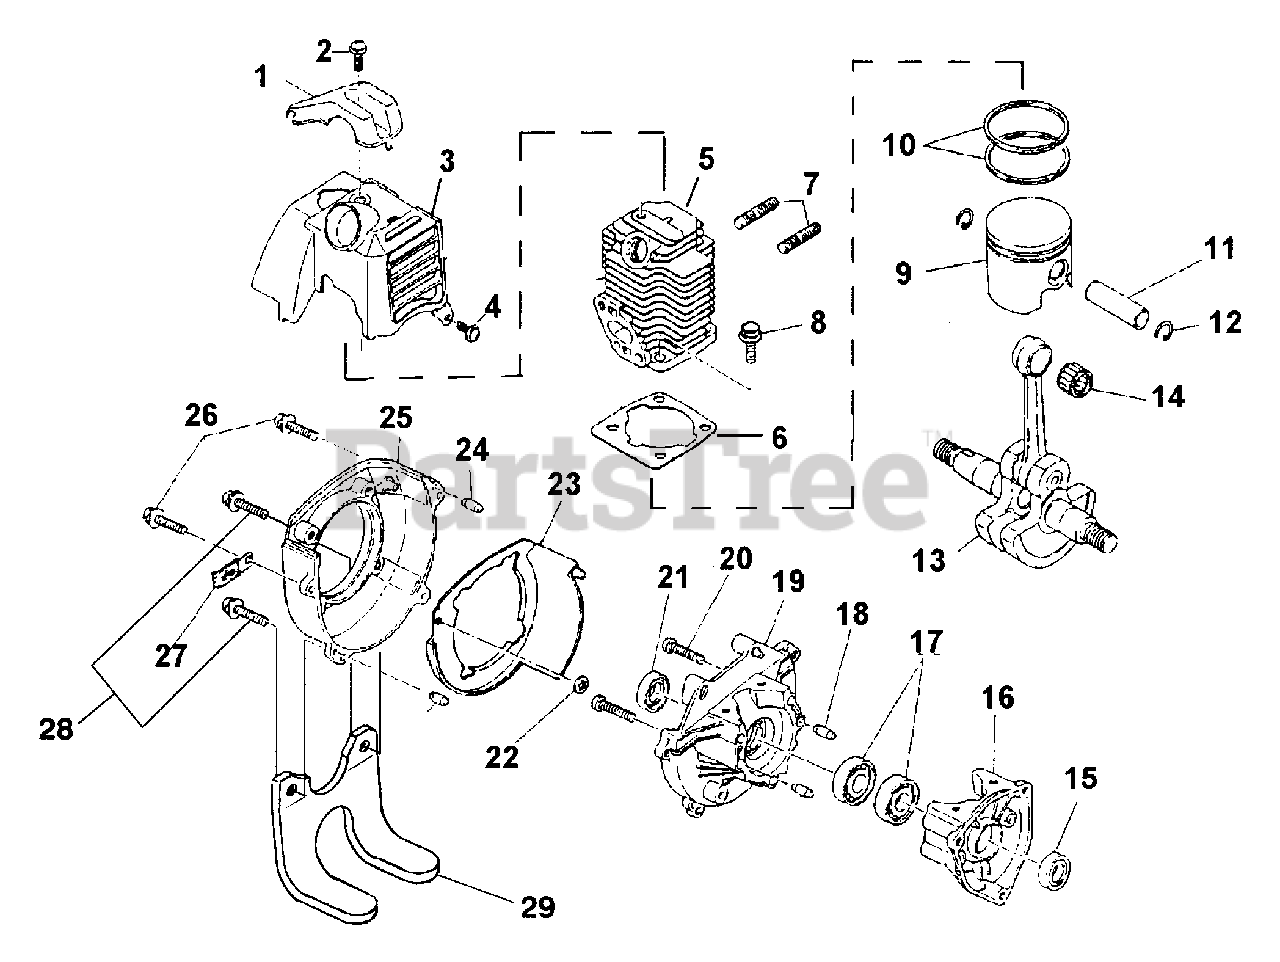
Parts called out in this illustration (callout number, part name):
1	GUARD, PLUG
2	SCREW & WASHER
3	COVER, TOP
4	SCREW & WASHER
5	CYLINDER ASSY
6	GASKET, CYLINDER
8	SCREW & WASHER
9	PISTON ASSY
10	RING, PISTON
11	PIN, PISTON
12	CLIP, PISTON PIN
13	CRANKSHAFT ASSY
15	OIL SEAL
16	CASE, STARTER
18	PIN, DOWEL
19	CASE, DRIVE
20	SCREW
21	OIL SEAL
24	PIN, DOWEL
25	CASE, FAN
26	BOLT & WASHER
28	BOLT & WASHER
29	ENGINE STAND
